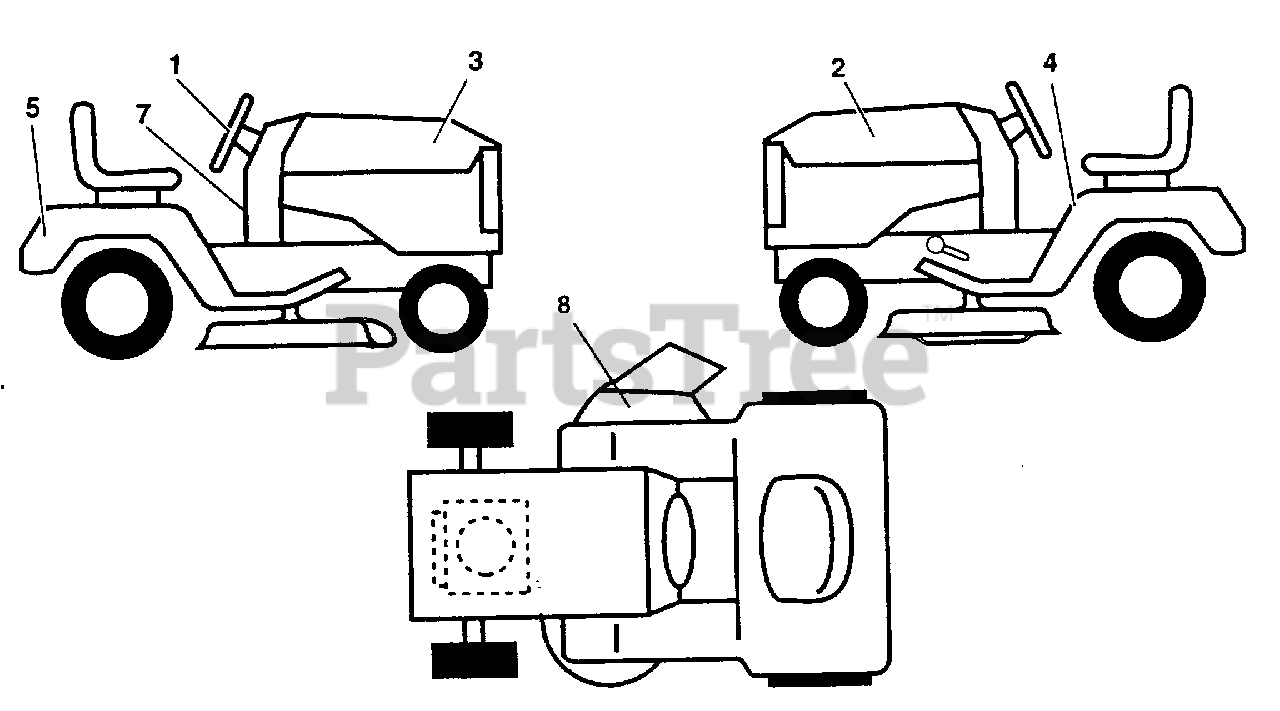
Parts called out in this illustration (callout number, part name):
1	Decal, Insert, Steering
2	Decal, Hood L.H.
3	Decal, Hood, R.H.
4	Decal, Caution
5	Decal, Logo, Fender
7	Decal, Oper. Inst. Eng./Fr.
8	Decal, Warning
